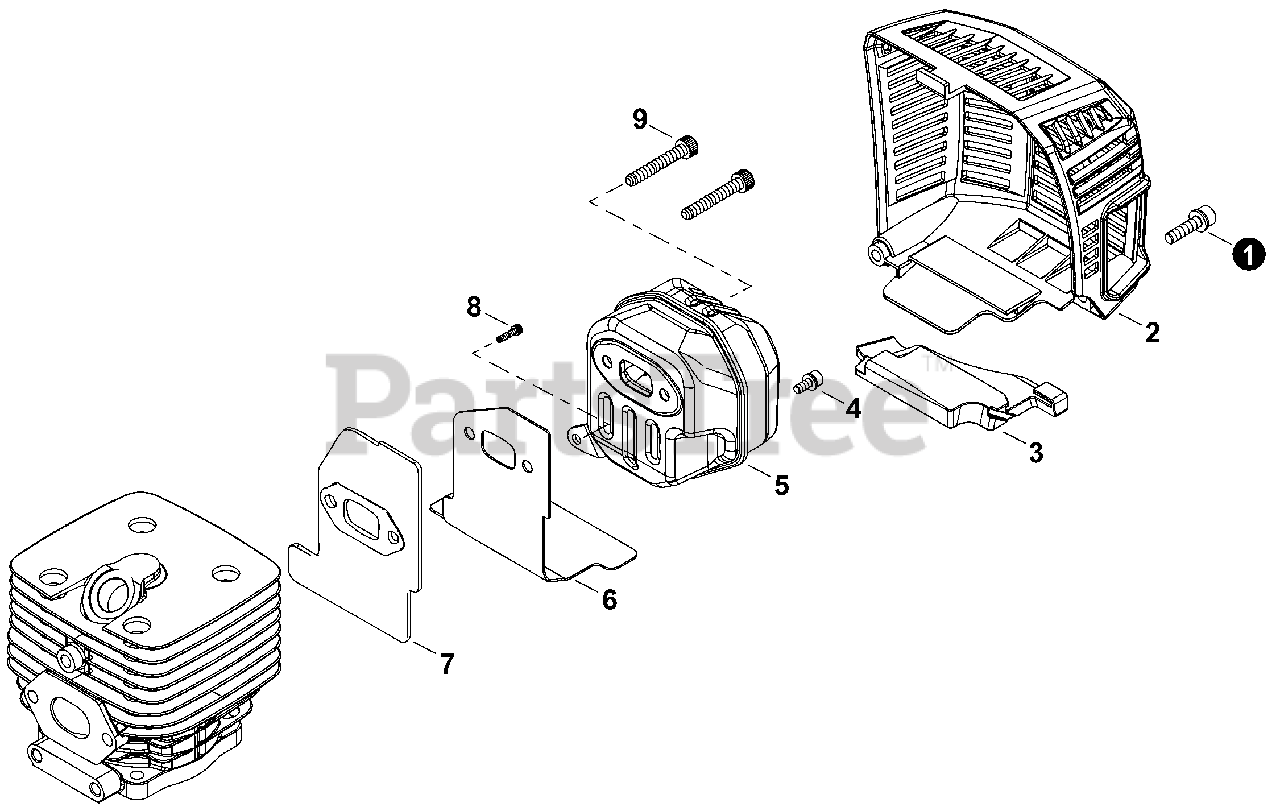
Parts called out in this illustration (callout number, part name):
1	BOLT, TORX 5x25
2	COVER, MUFFLER
4	BOLT, TORX 4x8
5	MUFFLER
6	HEAT SHIELD, EXHAUST
7	GASKET, EXHAUST
8	BOLT, TORX 5x12
9	BOLT, TORX 6x20
